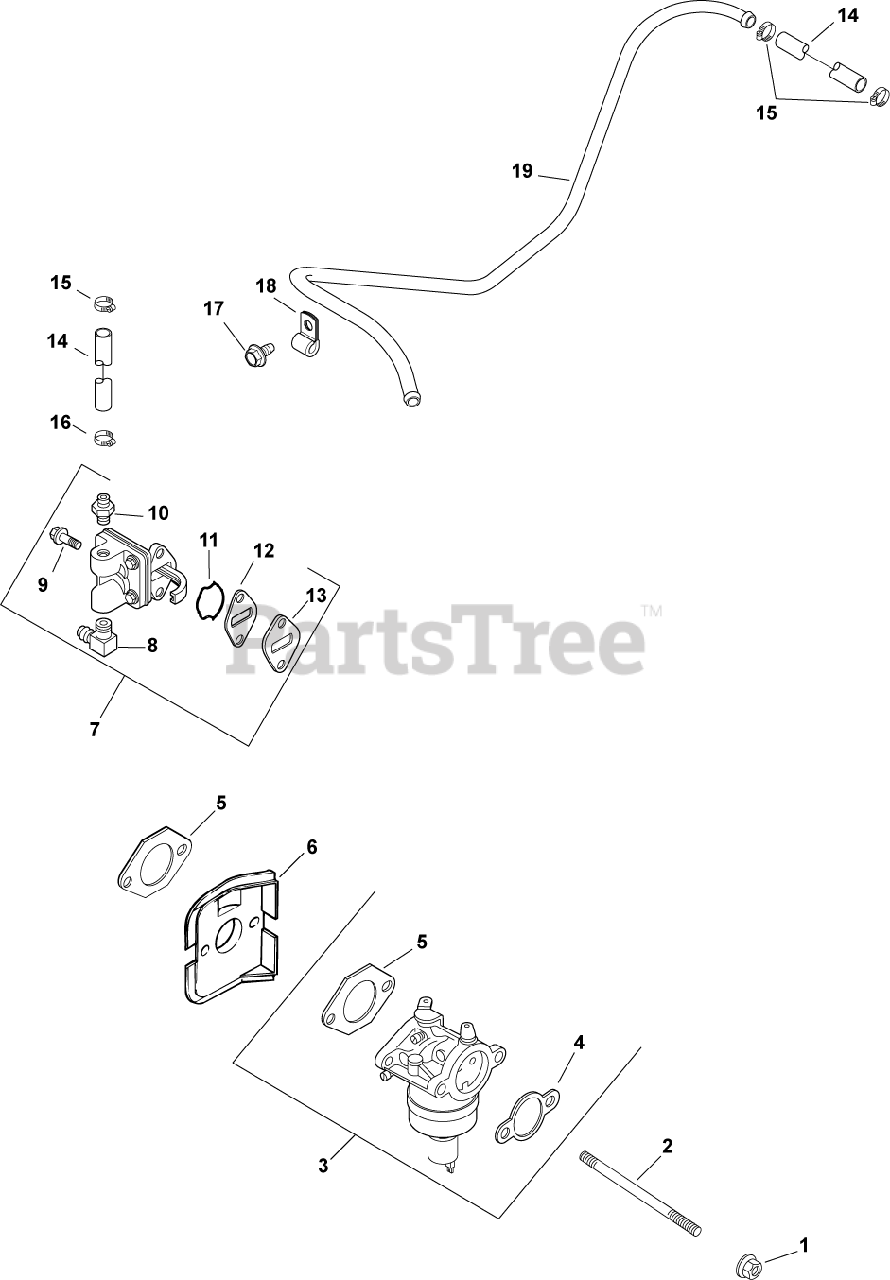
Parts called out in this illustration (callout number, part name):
1	NUT, FLG M6X1.0
2	STUD,M6X1.0X116
3	KIT, CARBURETOR w/GASKETS
4	GASKET, AIR CLEANER BASE
5	GASKET, CARBURETOR
6	DEFLECTOR, HEAT - DISCONTINUED
7	KIT, FUEL PUMP
8	CONNECTOR, 90 DEG. HOSE
9	SCREW,FLG THD FRM M6X1.0X20-(#25086396S)
10	KIT, STRAIGHT FITTING
11	O-RING, FUEL PUMP
12	GASKET, FUEL PUMP
13	SPACER, FUEL PUMP
14	HOSE,LW PERM.FUEL 24.00"-USE 25 111 81-S
15	CLAMP, HOSE (KM)-USE 25 237 31-S
16	CLAMP, BAND SPRING HOSE-(#2523737S)
17	SCREW, FLG THD FRM M5X.8X10
18	CLIP, TUBE & WIRING (KM)
19	LINE, FUEL
1275736-S	KIT, THROTTLE SHAFT BEARING
